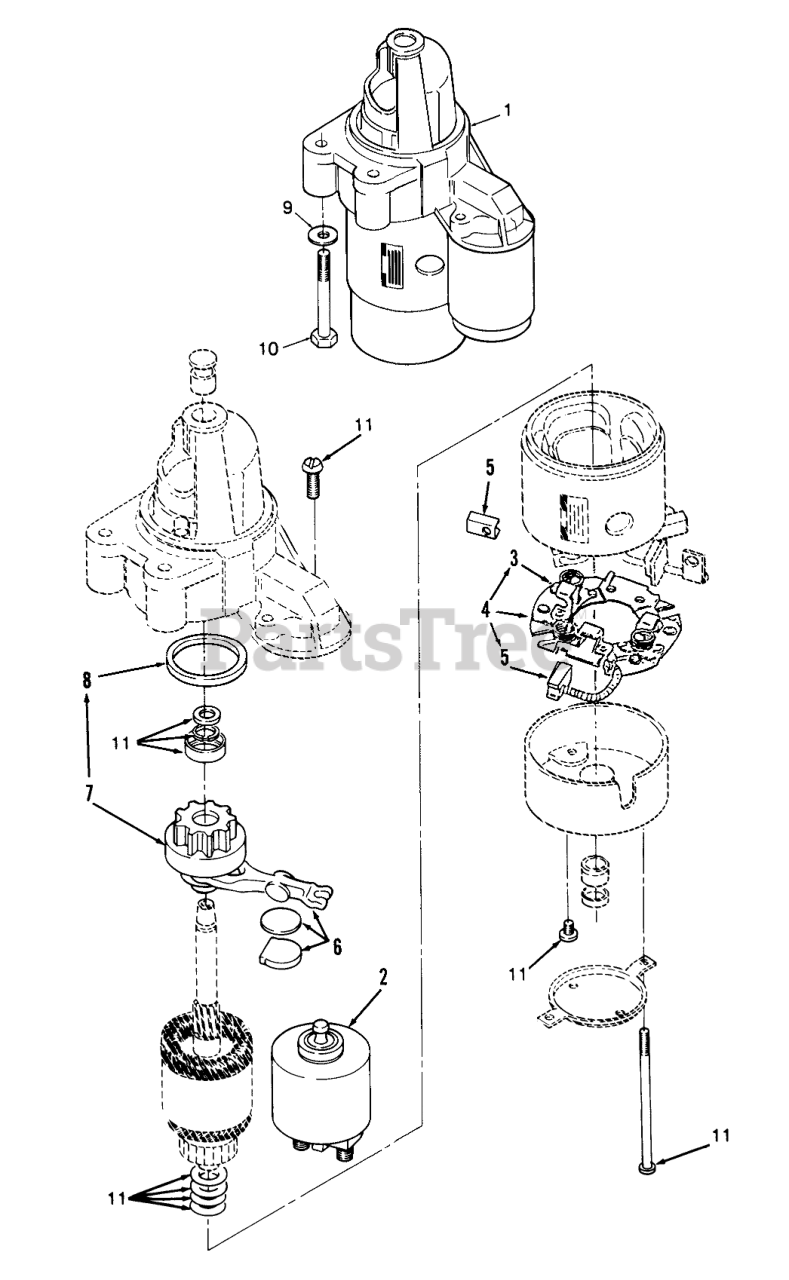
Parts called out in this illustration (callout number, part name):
1	Starter Assy
2	Starter Solenoid kit (Includes Solenoid, Spring and Plunger)
3	SPRING-BRUSH
4	Brush Holder (Includes Brush Holder w/ Negative Brush)
5	Brush kit (Includes Positive Brush (2) and Negative Brush w/ Pigtail)
6	Starter Shift Lever Kit (Includes Shift Lever Wear Plate and Rubber Plug)
7	Starter Clutch (Includes Pinion Gear w/ Clutch)
8	Dust Seal
9	WASHER
10	Bolt
11	Hardware Kit (Includes Solenoid Screws (2), Brush Holder Screws (2 Thru Bolts (2), Armature Shims (2), Pinion Stop Collar and Pinion Retaining Ring)
